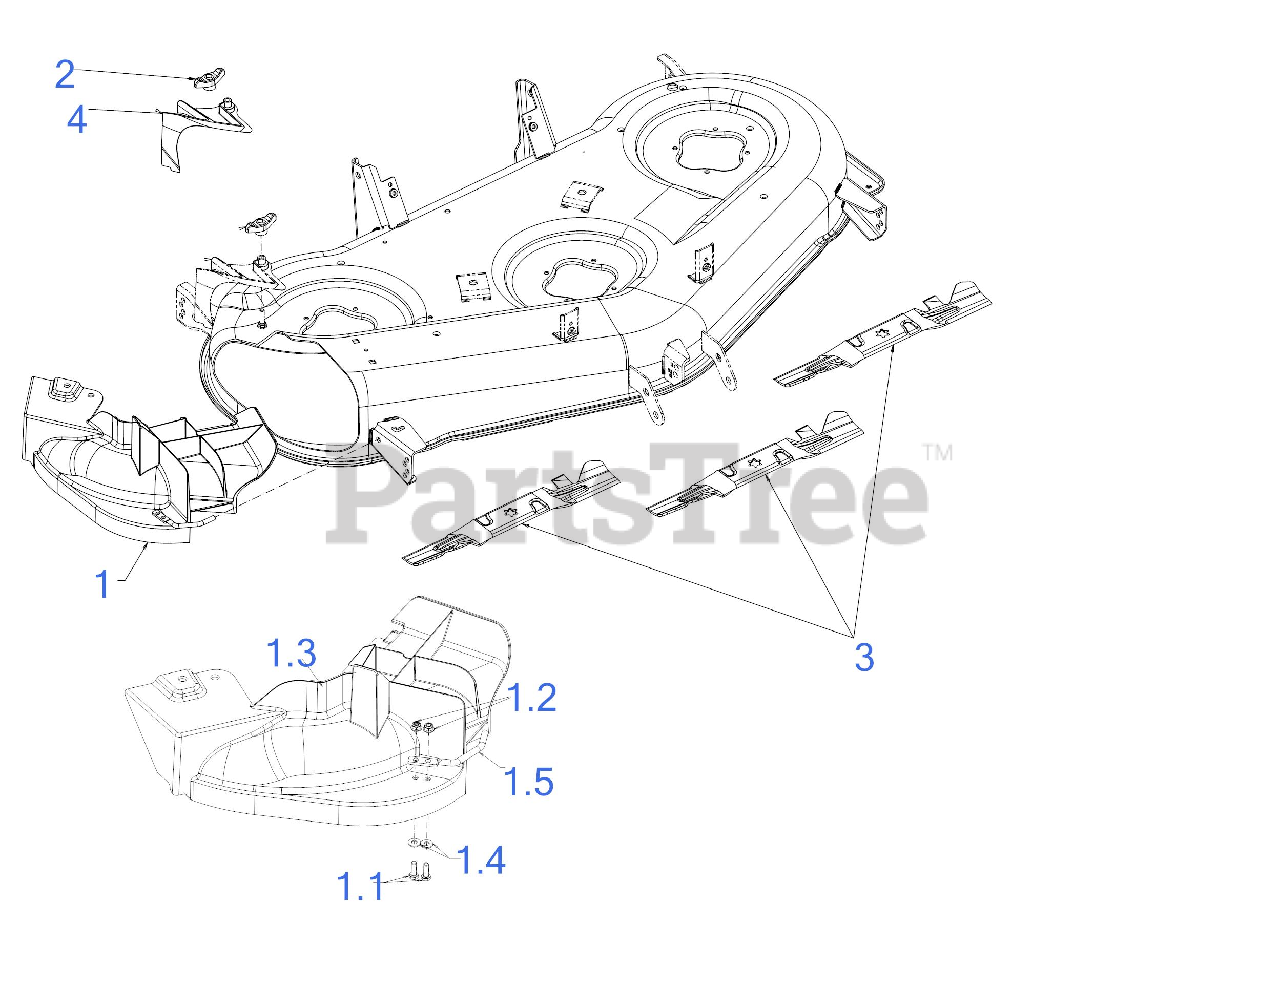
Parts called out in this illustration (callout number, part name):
1	MULCH PLUG ASSEMBLY
1.1	SCREW-HEX 1/4-20X.75 GR5
1.2	FLANGE LOCK NUT
1.3	MULCH PLUG
1.5	MULCH PLUG MOUTING ROD
2	WING KNOB 5/16-18
3	XTREME BLADE SET
4	CHUTE ADAPTER
